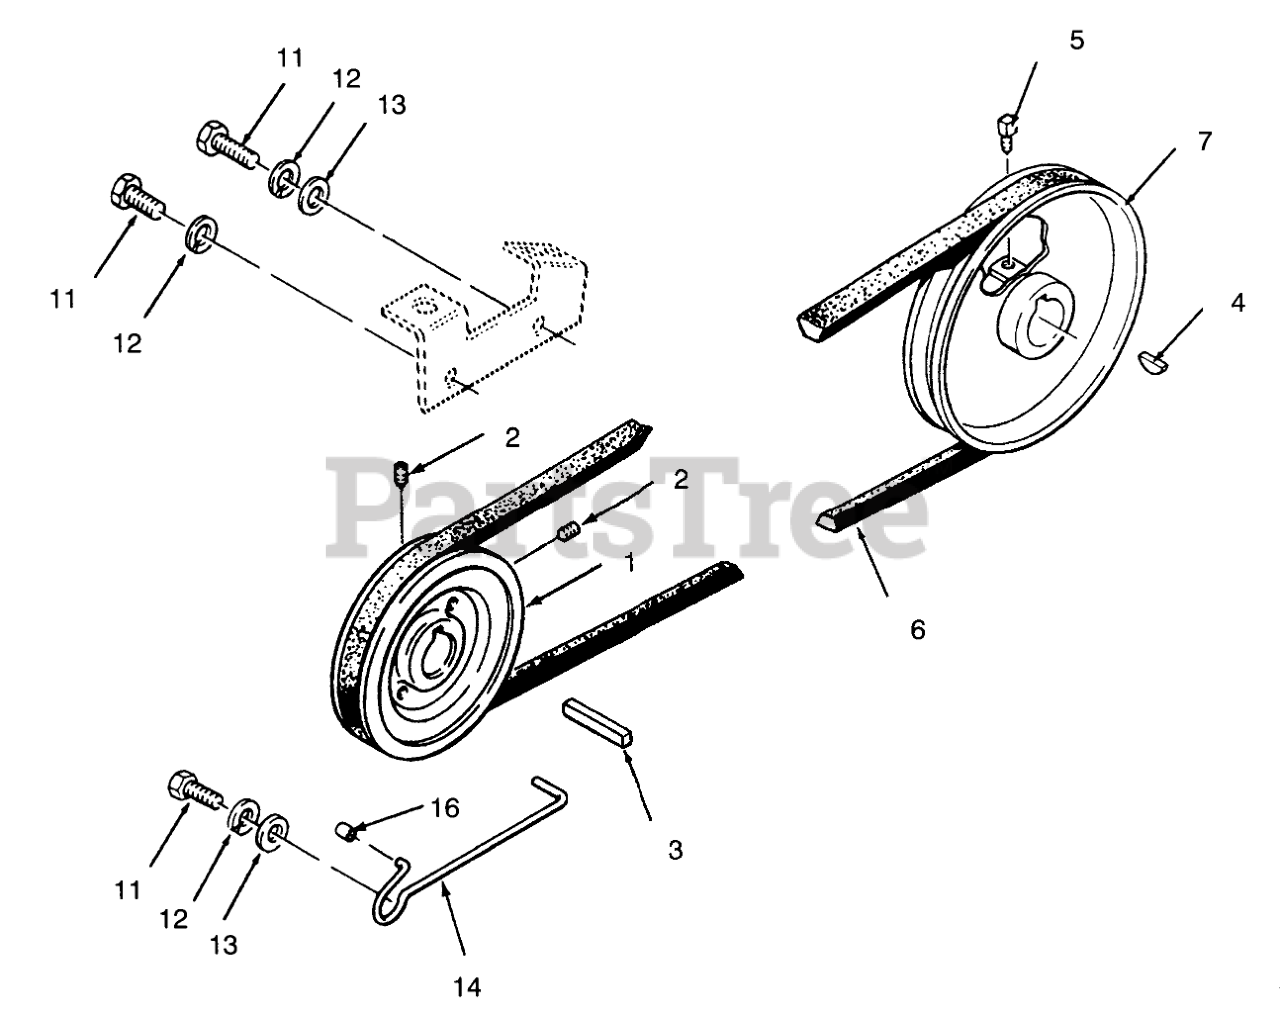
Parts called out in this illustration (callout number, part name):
1	PULLEY
2	SCREW-SET, HSH
4	KEY-HI PRO
5	SCREW-SQH
6	V BELT
7	PULLEY-TRANSMISSION
11	SCREW-HH
12	WASHER-LOCK
13	WASHER-FLAT
14	GUIDE BELT
